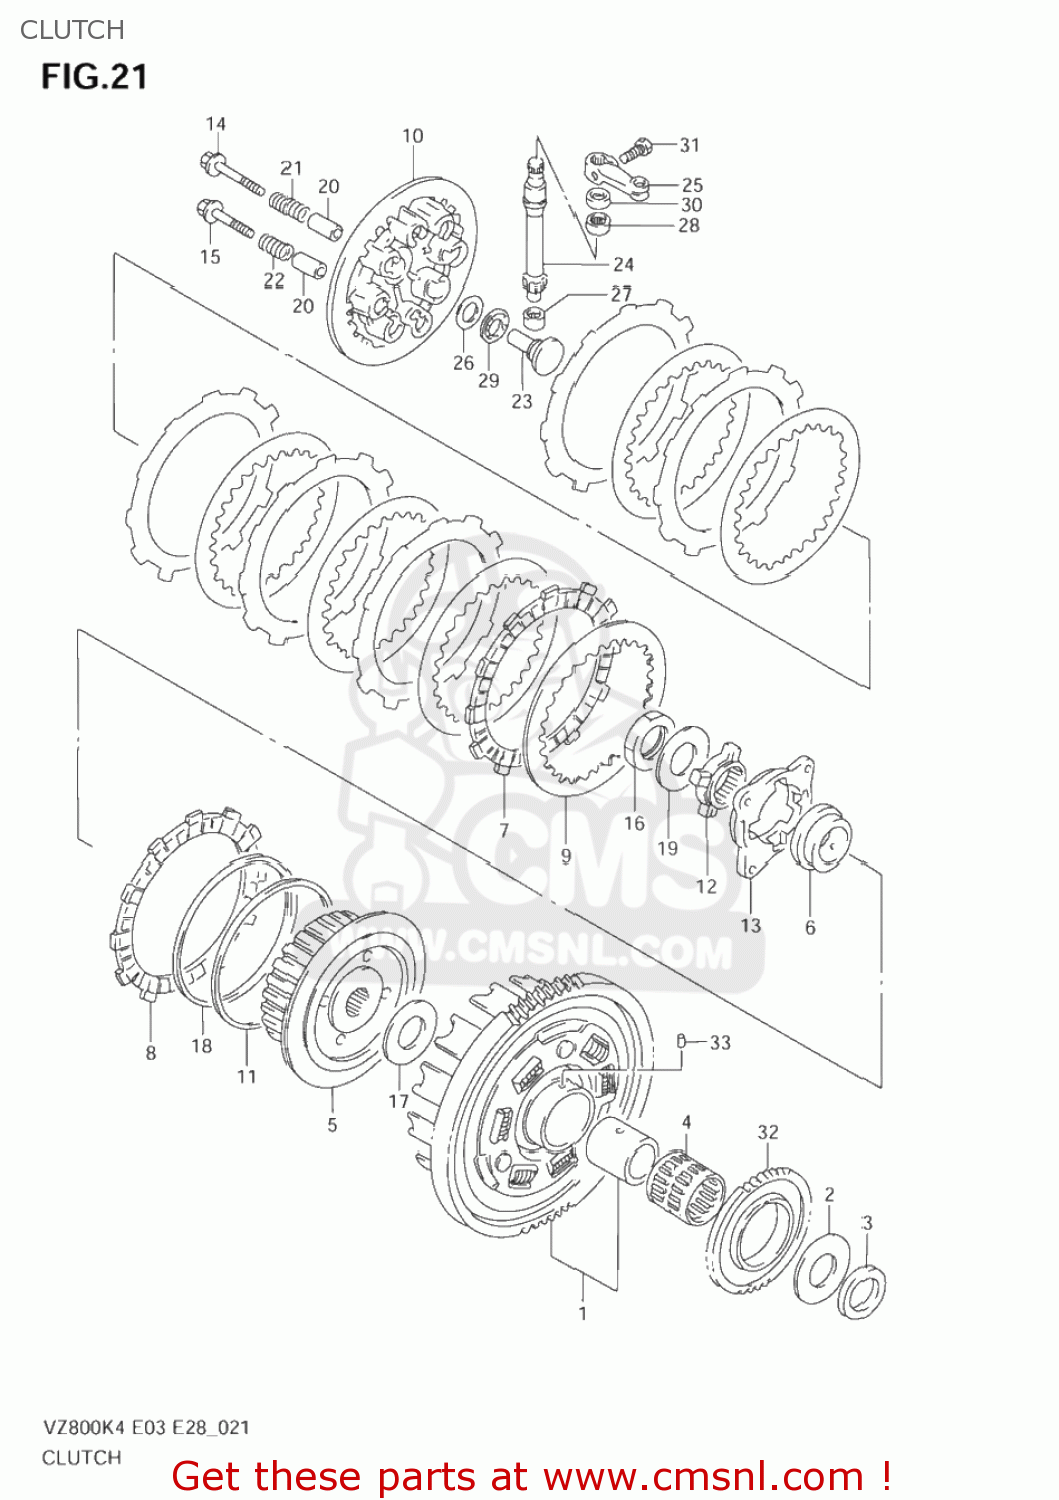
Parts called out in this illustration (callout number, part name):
1	GEAR ASSY,PRI DRIVEN
2	WASHER(25X54X2.5)
3	SPACER(25X38X6.5)
4	BEARING(35X40X35.8)
5	HUB,CLUTCH SLEEVE
6	SPACER,CLUTCH SLEEVE HUB
7	PLATE,CLUTCH DRIVE (NAS)
8	PLATE,CLUTCH DRIVE(T:3.5) (NAS)
9	PLATE,CLUTCH DRIVEN(T:1.6) (NAS)
10	DISC,CLUTCH PRESSURE
11	SEAT,WAVE WASHER(T:1.4)
12	CAM,CLUTCH NO.1
13	CAM,CLUTCH NO.2
14	BOLT(6X40)
15	BOLT(6X32.5)
16	NUT
17	WASHER(25X60X2.5)
18	WASHER
19	WASHER
20	SPACER(6.5X9X24.1)
21	SPRING
22	SPRING
23	RACK,CLUTCH RELEASE
24	PINION,CLUTCH RELEASE
25	ARM,CLUTCH RELEASE
26	WASHER(15.5X28X1)
27	BEARING(9X13X10)
28	BEARING(12X16X10)
29	BEARING(15X28X2)
30	SEAL,OIL(10X17X5)
31	BOLT
32	GEAR,OIL PUMP DRIVE(NT:47)
33	PIN(6X6)
